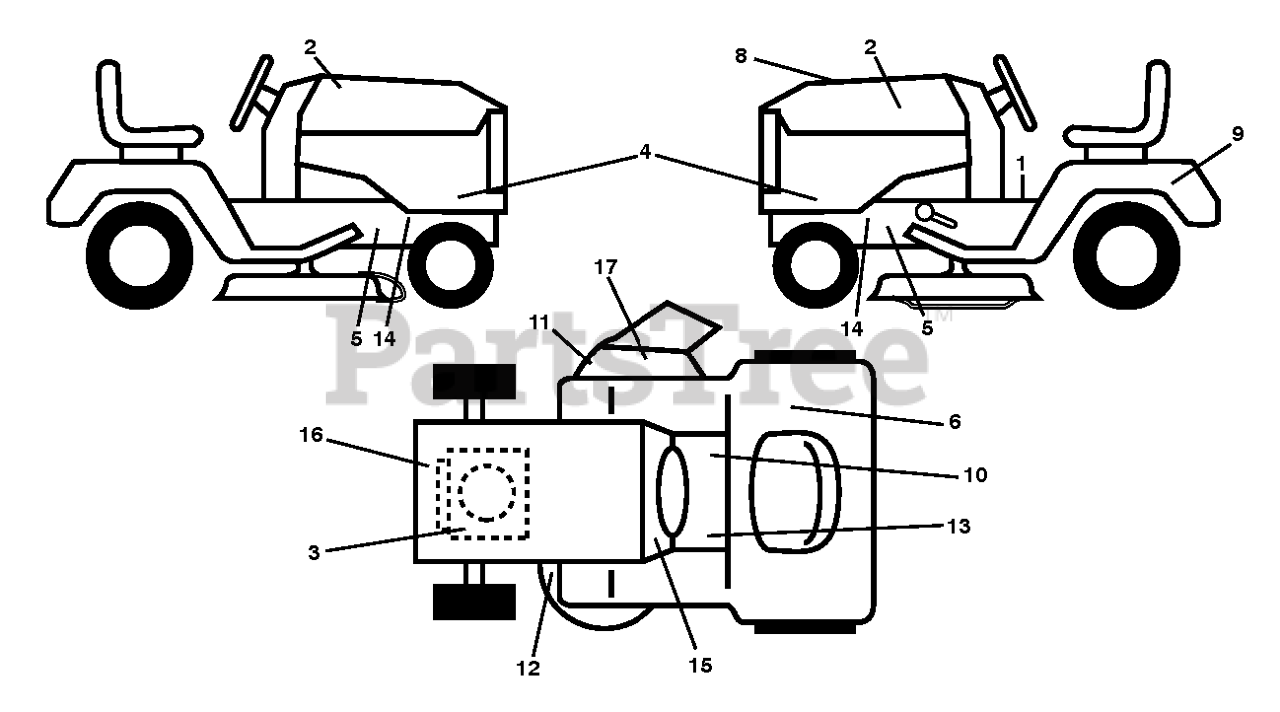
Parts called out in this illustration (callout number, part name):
1	DECAL.READ.OWN.MAN.SYMBOL.LT
2	DECAL.BADGE.170MM.TEXTLOGO.
3	DECAL.ENGINE.WARNING
5	DECAL.CHASSIS.HOT.MUFFLER
6	DECAL.CERTIFICATION.6MIL.100D
7	DECAL.CUTFINGER.CE.02
8	DCL.RPL.BSM31.INTK.TLW.38.PMST
9	DECAL BTRY SYMBOLS
10	DECAL.PARKING.BRAKE.SADDLE.LT
11	DECAL.DFLCTR.WARNNG.CTFNGR.SYM
12	DECAL.DECK.SCH.36,38,94.NONCR
13	DECAL.FNDR.SDLE.BRAKE.CLUTCH.6
14	DECAL.WARNING.SERVCE/FIRE
15	DECAL.SNOWFLAKE.MS498.HUSQ
16	DECAL.ENG.BS.SER4155.RS.382023
